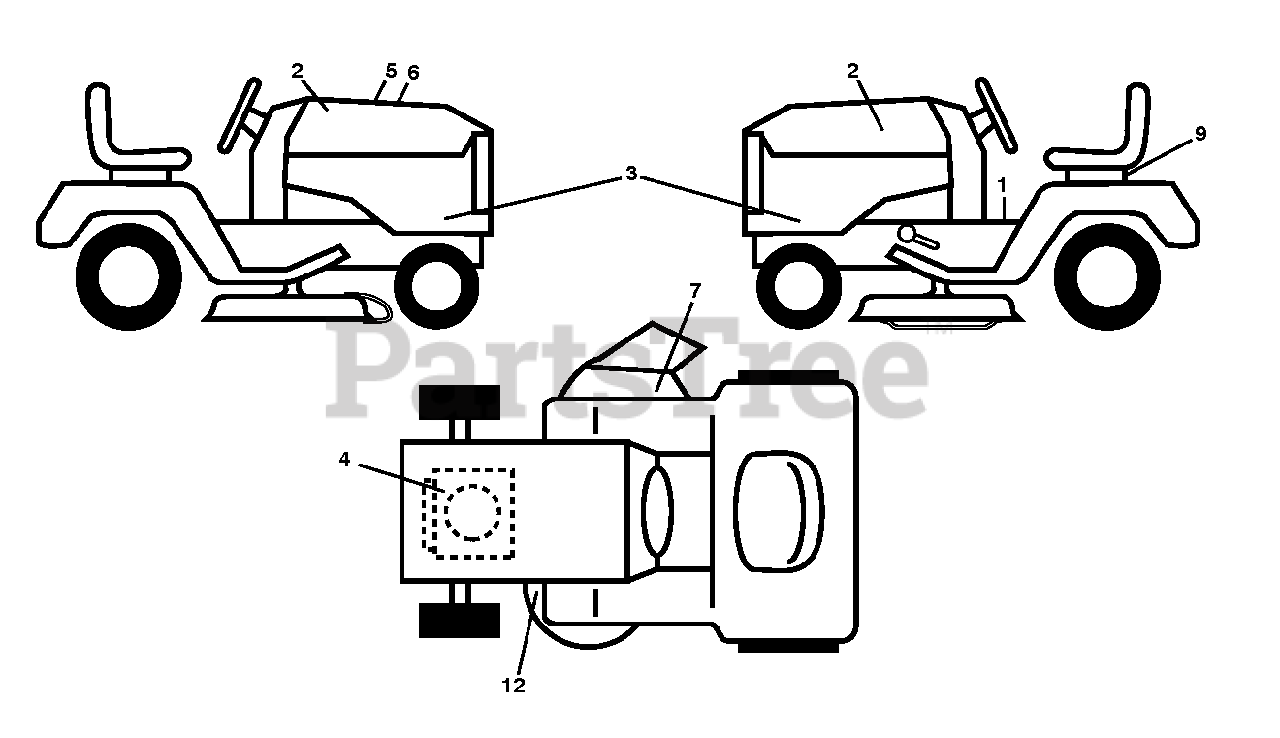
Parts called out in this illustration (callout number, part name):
1	DECAL.FENDER.WARNING.ENG
2	RP.DECAL.BADGE.170MM.TEXTLOGO
3	Decal, Side Panel YTH22V42
4	DECAL, ENGINE HP
5	DECAL.WARNING.CUST.RESP.E85.
6	Decal, Replacement BSM44
7	DECAL.WARN.KEEP.HAND.AWAY
9	DECAL BTRY SYMBOLS
12	DECAL V BELT SCHEMATIC
